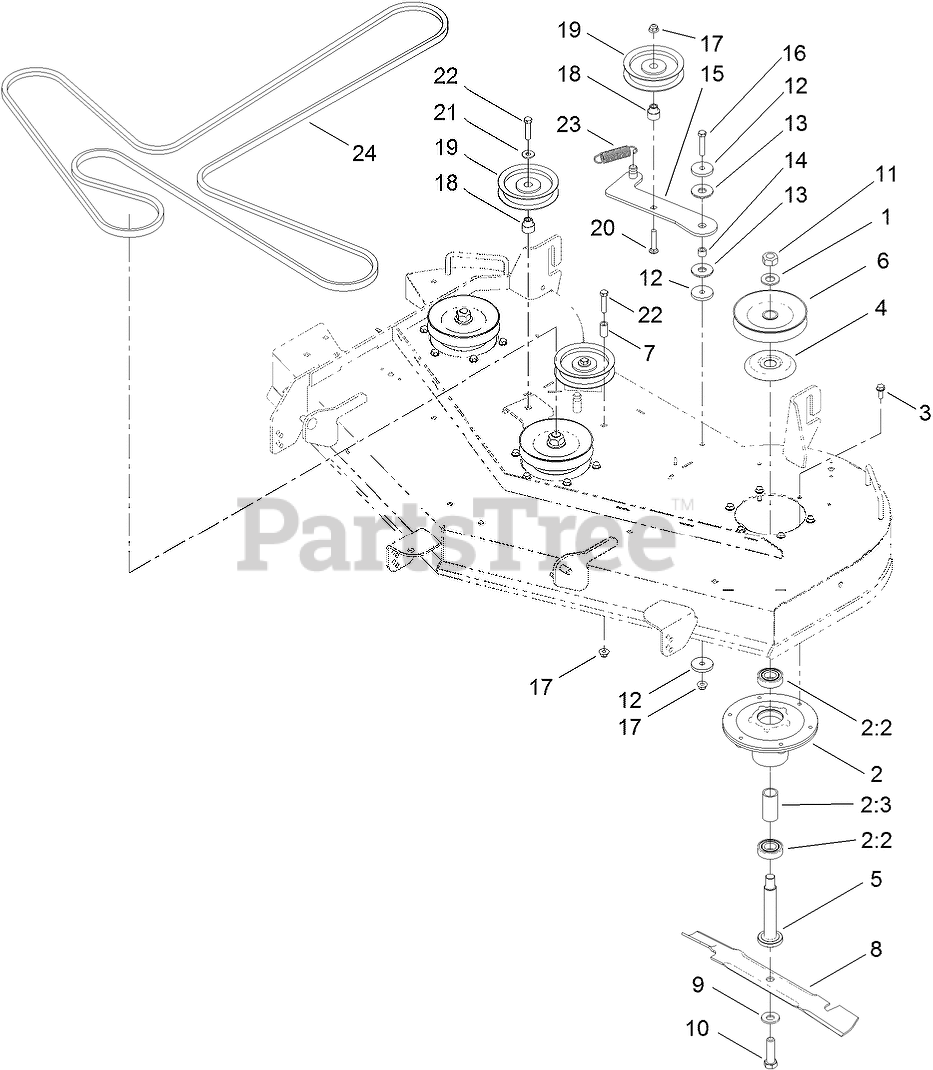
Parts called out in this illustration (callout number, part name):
1	WASHER
2	SPINDLE ASM
2:2	BEARING-BALL
2:3	SPACER-BEARING
3	SCREW-TAPTITE
4	SHIELD-BEARING
5	SHAFT-SPINDLE
6	PULLEY
7	SPACER
8	BLADE-HI FLO
9	WASHER-BELLEVILLE
10	SCREW-BLADE
11	NUT-HEX
12	WASHER-PLAIN
13	WASHER-FRICTION, COMPOSITE
14	BUSHING-LEVER, LIFT
15	ARM-IDLER
16	SCREW-HH
17	NUT-HF, NI
18	BUSHING-IDLER
19	PULLEY-IDLER
20	SCREW-CARR
21	WASHER-HARDENED
22	SCREW-HH
23	SPRING-EXTENSION
24	V-BELT
